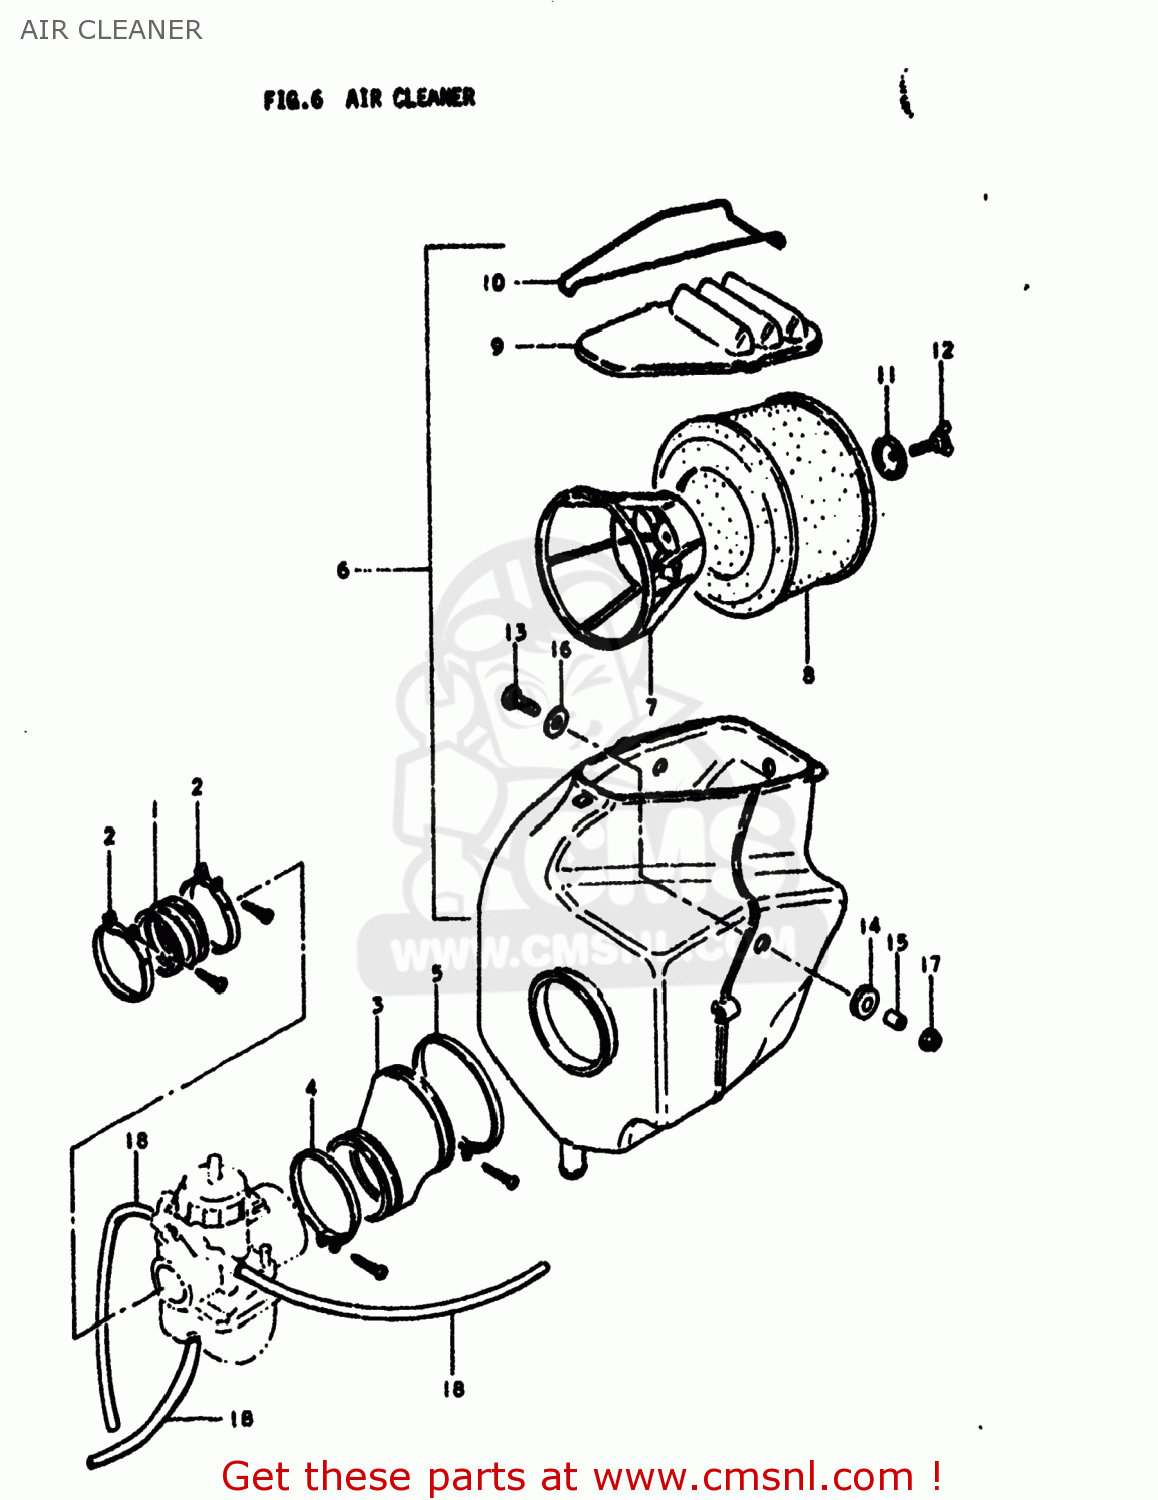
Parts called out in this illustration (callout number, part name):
1	PIPE,INTAKE
2	CLAMP
3	TUBE,AIR CLEANER OUTLET
4	CLAMP
5	CLAMP
6	CLEANER ASSEMBLY,AIR
7	HOLDER,FILTER
8	ELEMENT,AIR CLEANER
9	CAP,AIR CLEANER
10	O RING
11	HOLDER,FILTER
12	WING BOLT,AIR CLEANER
13	BOLT
14	CUSHION
15	SPACER (6.1X9X9)
16	WASHER (6.5X20X1.2)
17	NUT
18	HOSE
